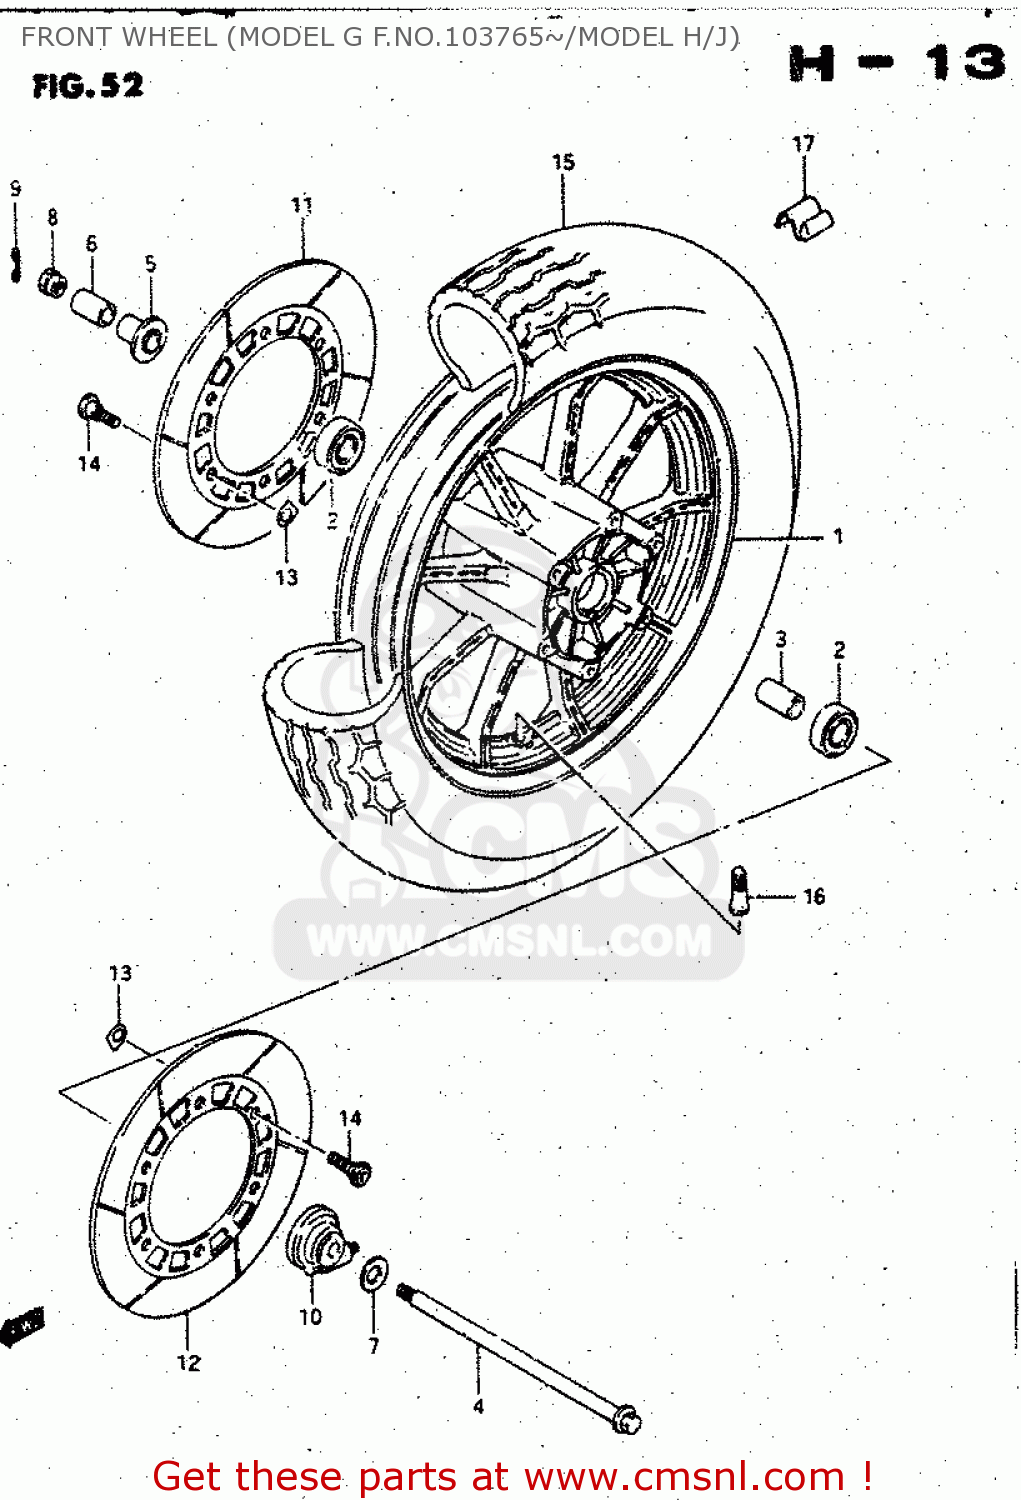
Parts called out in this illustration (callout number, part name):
1	WHEEL,FRONT (MT2.50X16)
2	BEARING
3	SPACER
4	AXLE,FRONT
5	SPACER,FR HUB BEARING,R
6	SPACER,FR AXLE,R
7	WASHER
8	NUT (12MM)
9	PIN,FRONT AXLE
10	BOX ASSY,SPEEDOMETER GEAR
11	DISC,FRONT BRAKE,RIGHT
12	DISC,FR BRAKE,L
13	SHIM,BRAKE DISC
14	BOLT(8X25.5)
15	TIRE,FRONT
16	VALVE,TIRE
17	BALANCER,WHEEL
